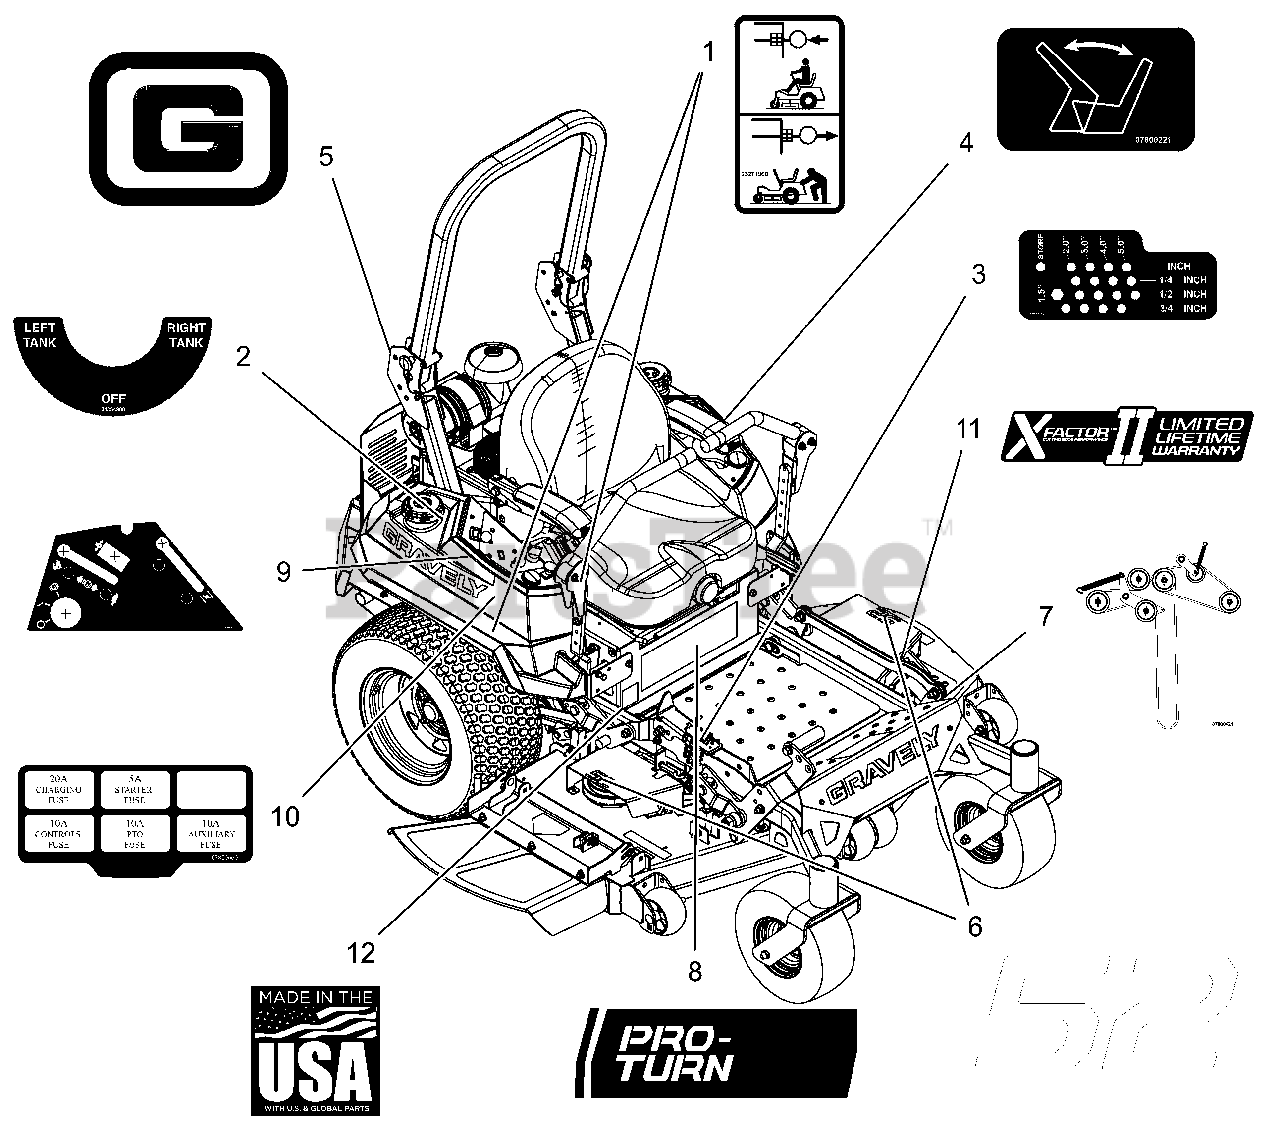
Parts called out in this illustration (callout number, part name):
1	DECAL, TRANSMISSION DISCONNECT
2	DECAL, FUEL VALVE
3	DECAL, HEIGHT OF CUT
4	DECAL - SEAT RELEASE
5	DECAL, GRAVELY BRAND
6	DECAL, 52"
7	DCL,BELT ROUTE-RH V-SIDE IDLER
8	DECAL, PRO-TURN 152
9	DECAL, NON-EFI CONTROL PANEL
10	DECAL, FUSE BLOCK
11	DECAL, X-FACTOR DECK
12	DECAL, MADE IN USA
